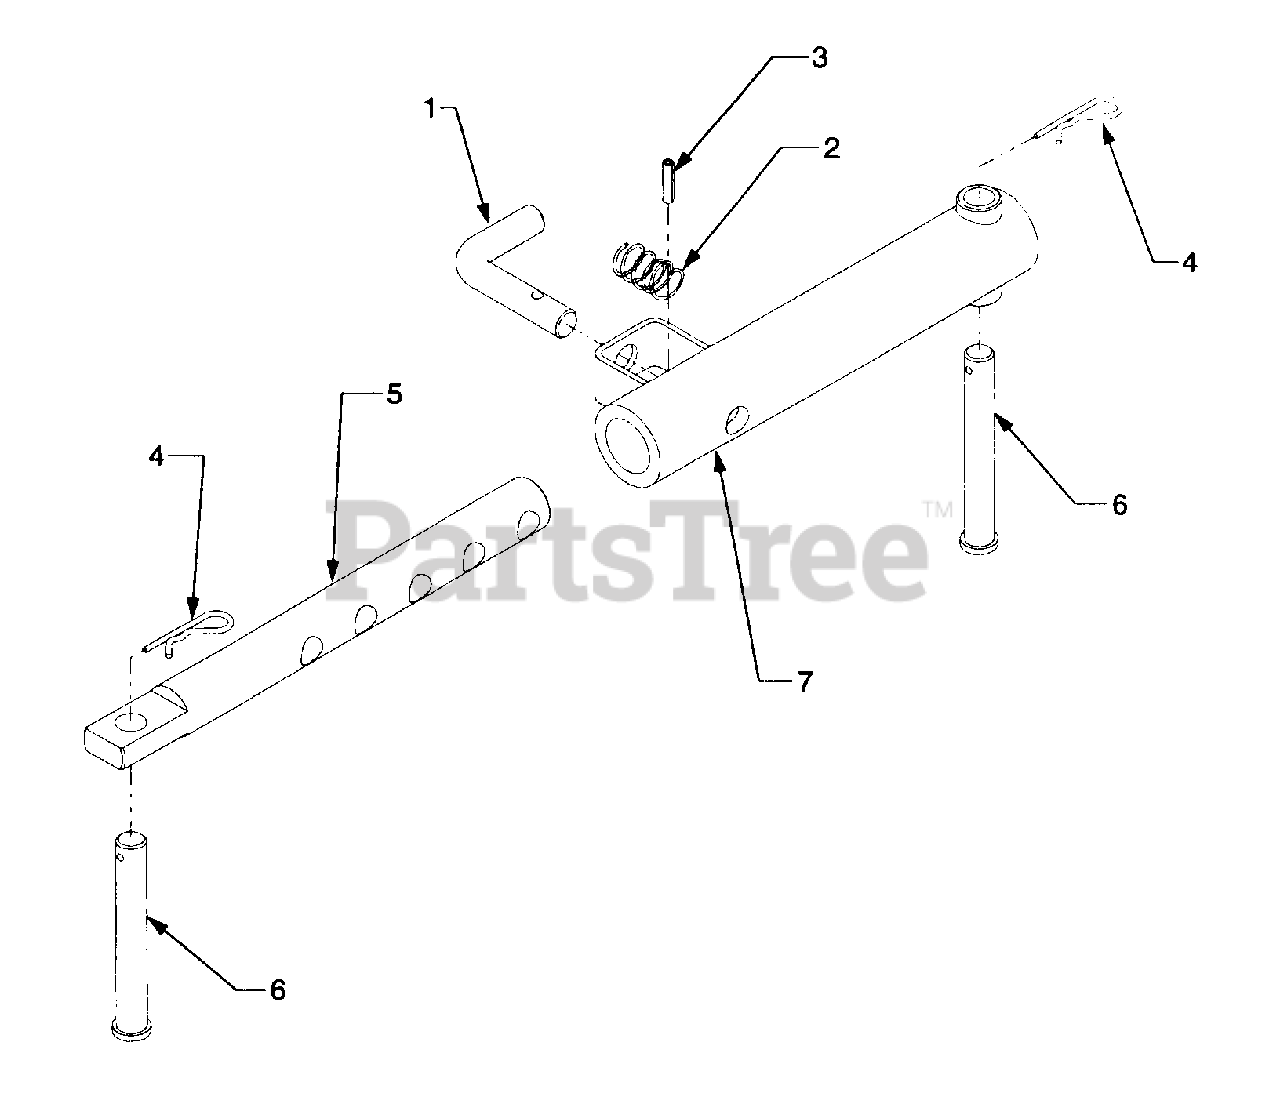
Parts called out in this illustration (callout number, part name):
1	Pin, Spring Detent
2	Spring, Compression
3	Pin, Hvy. Dty. Spirol, 3/16 x 3/4
4	Pin, Internal Cotter
5	Rod, Hitch Adjustment
6	Pin, Clevis
